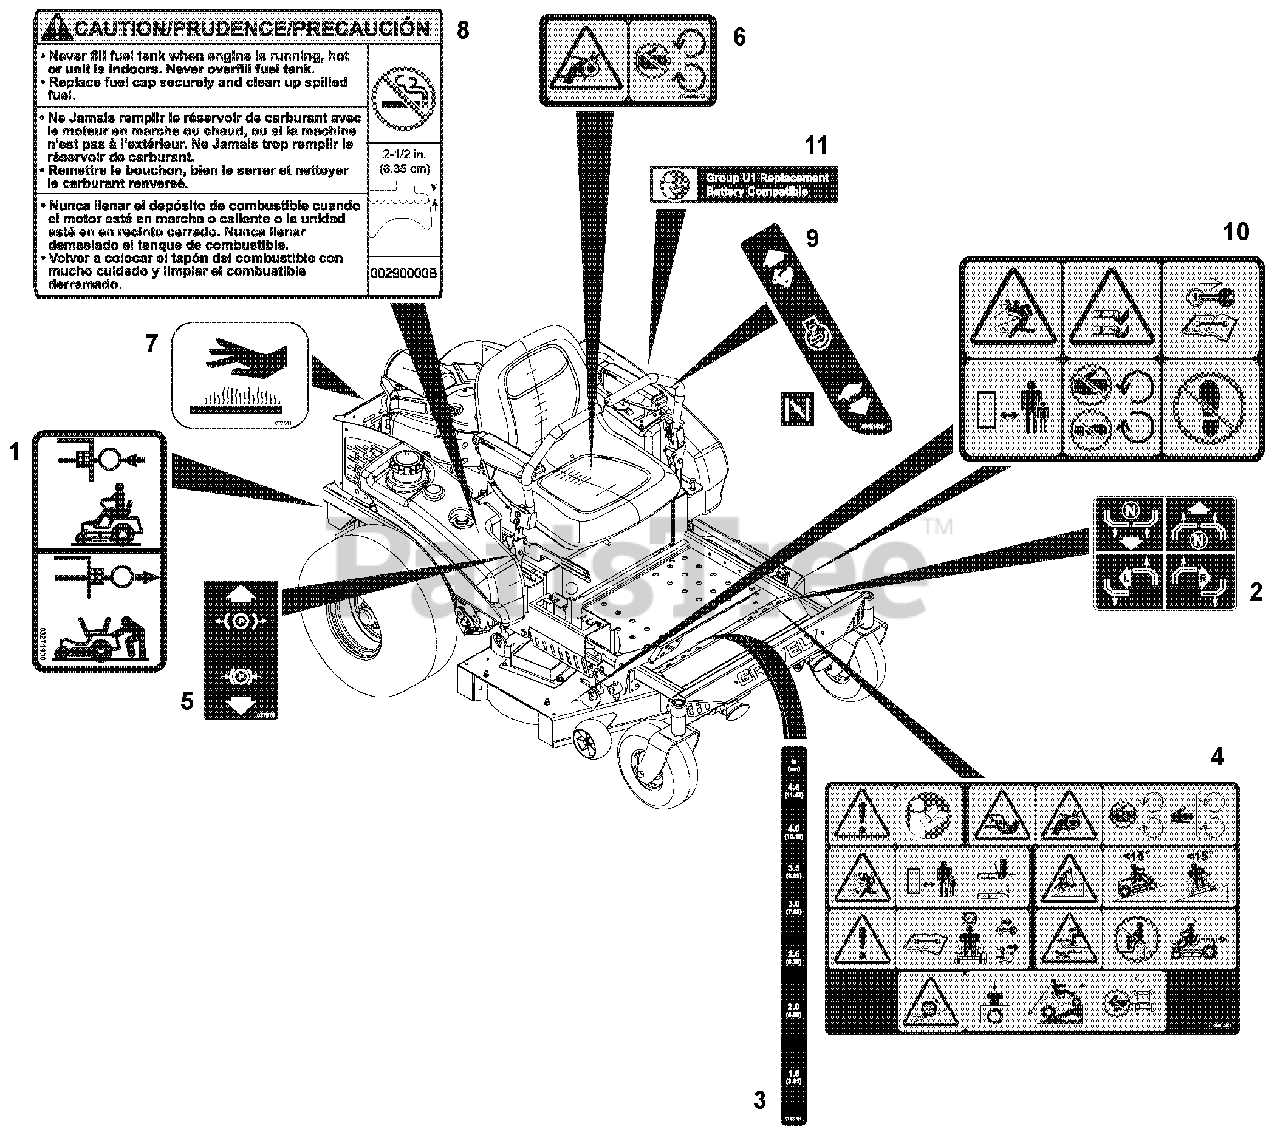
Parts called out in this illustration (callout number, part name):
1	Decal, Transmission Disconnect
2	Decal, Instructional Steering
3	Decal, Cut Height
4	Decal, Safety, Main
5	Decal, Parking Brake Lever
6	Decal, Safety, Guarding
7	Decal, Hot Surface
8	Decal, Fuel Warning
9	Decal, Control
10	Decal, Mower Deck Safety
11	Decal, Battery Replacement
